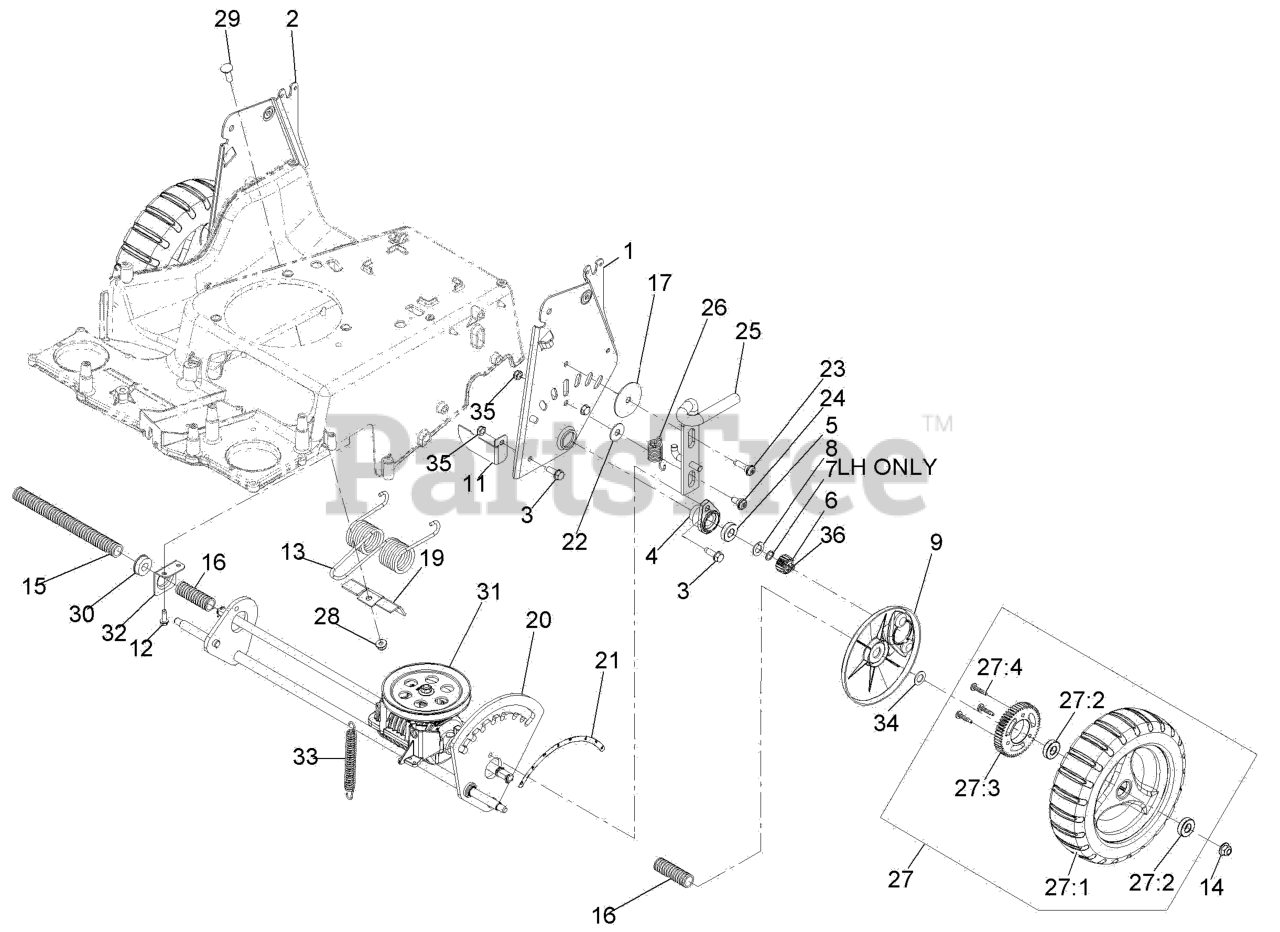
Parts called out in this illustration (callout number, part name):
1	LH HOC PLATE ASM
2	RH HOC PLATE ASM
3	SCREW-THD ROLL, HWH
5	BEARING-BALL
7	RING-RETAINING
8	WASHER-THRUST
9	COVER-GEAR
12	SCREW-HWHTF
13	SPRING-TORSION
14	NUT-HF, NI
15	CONDUIT-CONVOLUTED
16	CONDUIT-CONVOLUTED
17	WASHER-PLAIN
19	BRACKET
20	AXLE-REAR
21	DECAL-HOC, REAR
23	SCREW-SHOULDER, BHTF
24	BOLT-SHOULDER
25	LOCK-HEIGHT, ADJUST
26	SPRING-EXTENSION
27:2	BEARING-BALL
27:4	SCREW-DRIVE
28	NUT-HF, NI
29	BOLT-CARR
30	BEARING-BALL
31	TRANSMISSION KIT
33	SPRING-EXTENSION
34	WASHER-PLAIN
35	NUT-LOCK, NI
36	PIN-SNAP
